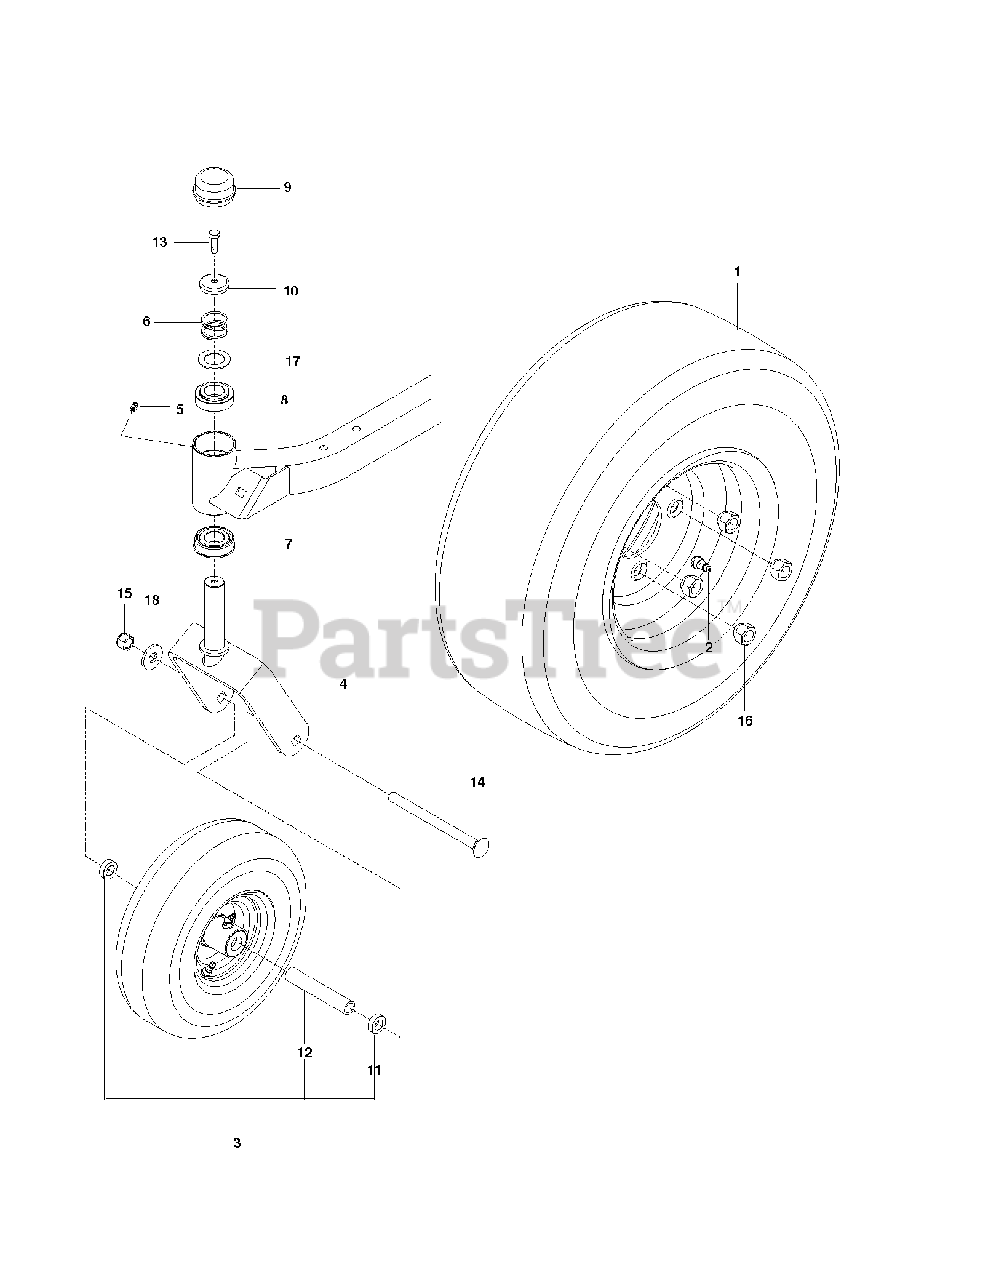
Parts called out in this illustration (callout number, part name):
1	WHEEL.A500.18 X 9.5-8.SILVER
2	VALVE STEM TR-412
3	WHEEL.11X4-5.K404LG.5X3W/4.188
4	YOKE.CASTER.ORANGE
5	ZERK, 3/16, DRIVE IN
6	SPRING, CASTER
7	BEARING FLANGED
8	BUSHING, CASTER
9	GREASE CAP
10	CASTER.PLUG
11	SPACER, 5/16"
13	5/16-18X1 HHB G5W/NY
14	RHSNB 1/2-13 X 6.50 GR2 ZD
15	NUT 1/2-13 HEX CNTRLK GR 5 ZD
16	LUG NUT 1/2F
17	WASHER, 1.025 ID X 1.64
18	WASHER.9/16 X 1 3/8 X 12 GA.
